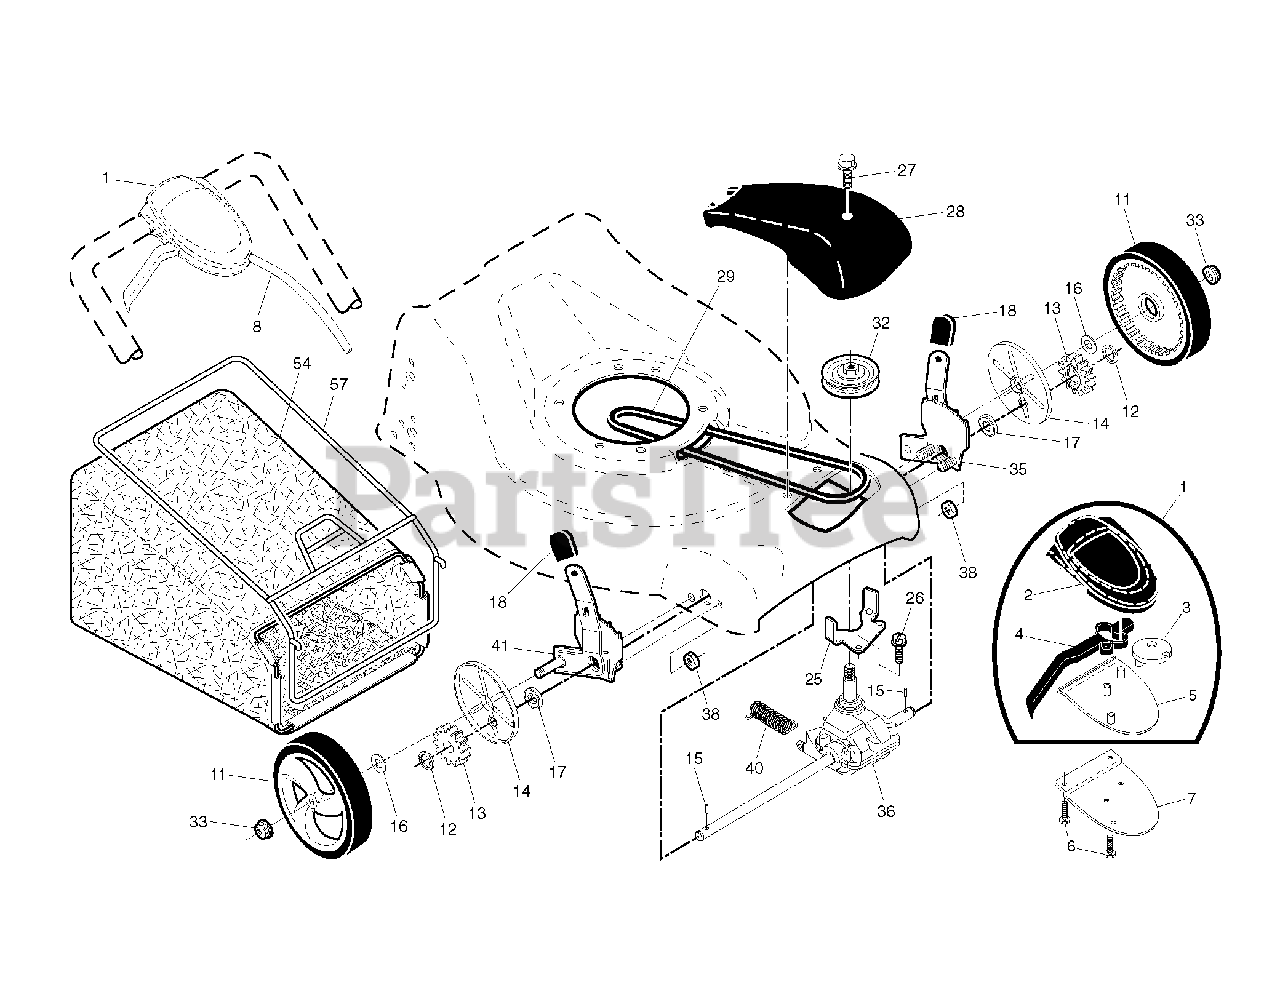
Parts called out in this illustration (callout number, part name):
2	COVER, TOP DRIVE CONTROL
3	PULLEY.CAM.DRIVE.CONTROL.EZ
5	COVER BOTTOM DRIVE CNTRL BLACK
6	SCREW, PHILLIPS HEAD 10 X 5/8
7	BRACKET.DRIVE.CONTROL.MOUNT
8	CABLE ASSEMBLY, DRIVE
12	E-RING 7/16 RE
13	PINION.14.TEETH.FGD
14	COVER.DUST.WHEEL
15	PAWL, DRIVE
16	WASHER FLUT
17	BEARING
18	SELECTOR KNOB
25	BELT KEEPER
27	SCREW, HEX HD TAPPING #10-24 1
29	BELT.DRIVE.FG
32	RP PULLEY.DRIVE.EZ
33	NUT.HEX.FLANGE.3/8-16.LOCKNUT
35	RP KIT, WHEEL ADJUSTER, LH
36	TRANSMISSION.21.FGD.HT.VST
38	LOCKNUT
41	KIT, WHEEL ADJUSTER, RH
57	FRAME.GBAG.21.FWGD
